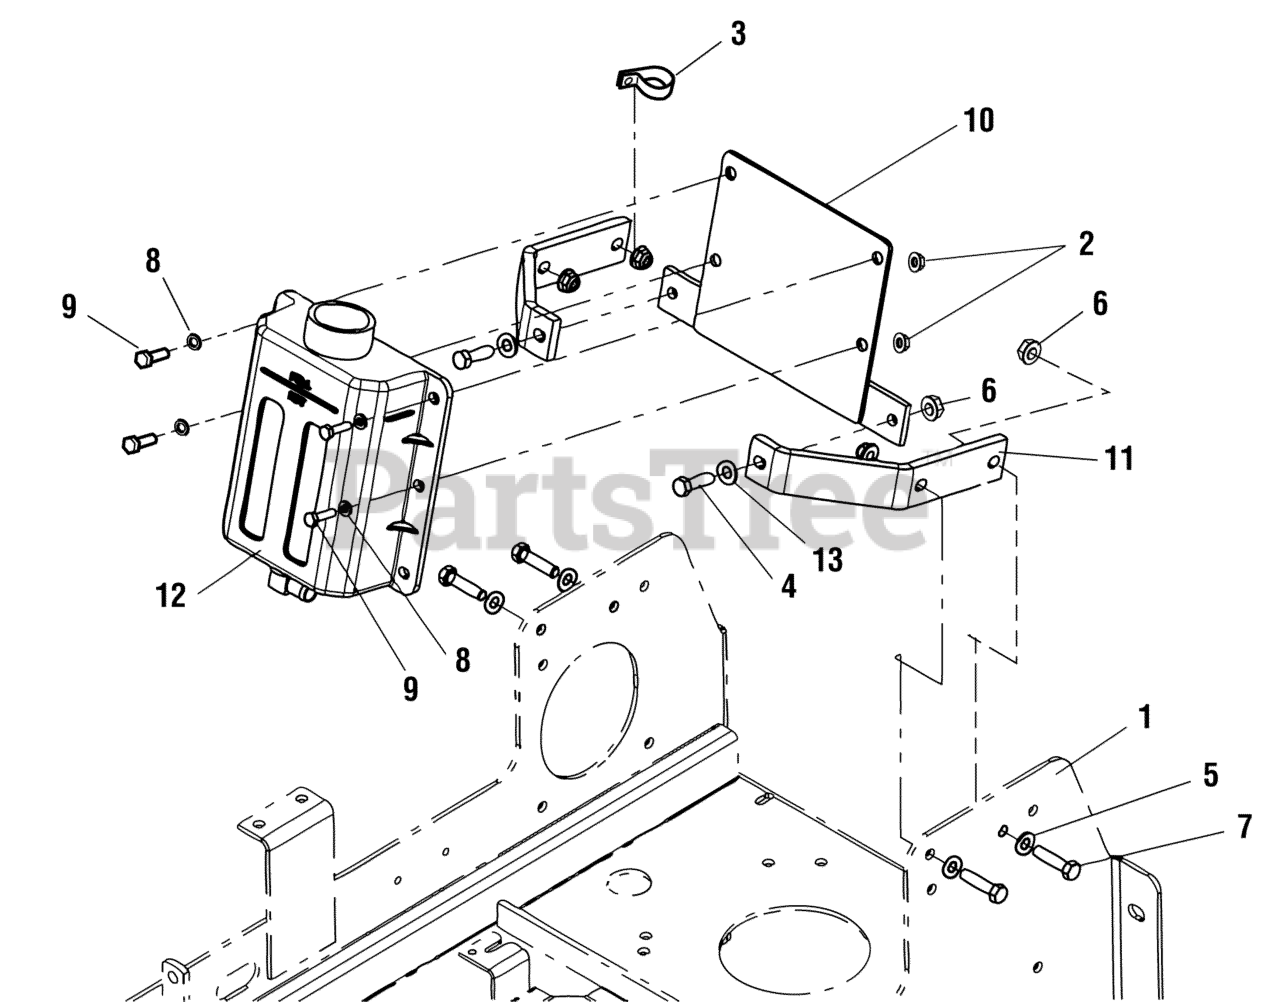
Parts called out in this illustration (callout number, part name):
1	MAIN FRAME
2	NUT, 1/4-20 HEX NYLOCK FLANGE
3	CLAMP, VINYL, 1"
4	BOLT, 3/8-16 X 1-1/4" GD5 CZ
5	WASHER, 3/8 SAE
6	NUT, 3/8-16 Hex Nylock Flange
7	BOLT, 3/8-16 X 1-1/2" GD5 CZ
8	WASHER, 1/4 SAE
9	BOLT, 1/4-20 X 3/4"
10	WELD, HYD TANK MOUNT
11	MOUNT BRACKET
12	HYDRAULIC TANK
13	WASHER, 3/8" GR. 9 FLAT
